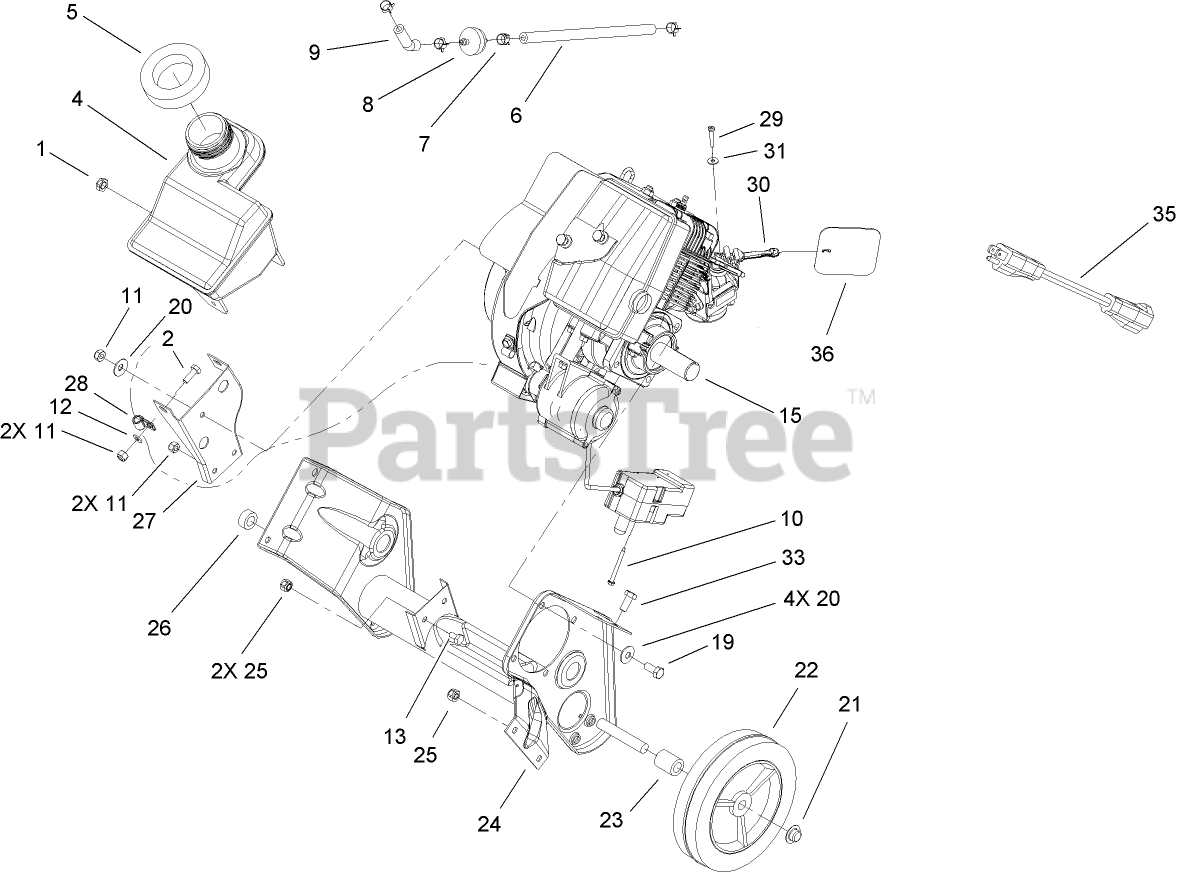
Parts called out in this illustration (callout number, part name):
1	NUT-LOCK, CONE
2	SCREW-HH
4	TANK-GAS
5	SEAL-FOAM
6	HOSE-FUEL
7	CLAMP-HOSE
8	FILTER-FUEL
9	HOSE-FUEL
10	SCREW-PLASTITE
11	NUT-LOCK, NI
12	WASHER-FLAT
13	SCREW-HH
15	Loose Parts Package
19	SCREW-HH
20	WASHER-BELLEVILLE
21	NUT-PUSH
22	WHEEL
23	SPACER-WHEEL
25	NUT-LOCK, NI
26	SPACER-WHEEL
27	BRACKET-SUPPORT, RECOIL
28	CLAMP
29	SCREW-PPH, PLASTITE
30	LEVER-CHOKE
31	WASHER-FLAT
33	SCREW-HH
35	CORD-EXTENSION (only on: 38078)
36	SHIELD-CHOKE HOLE
